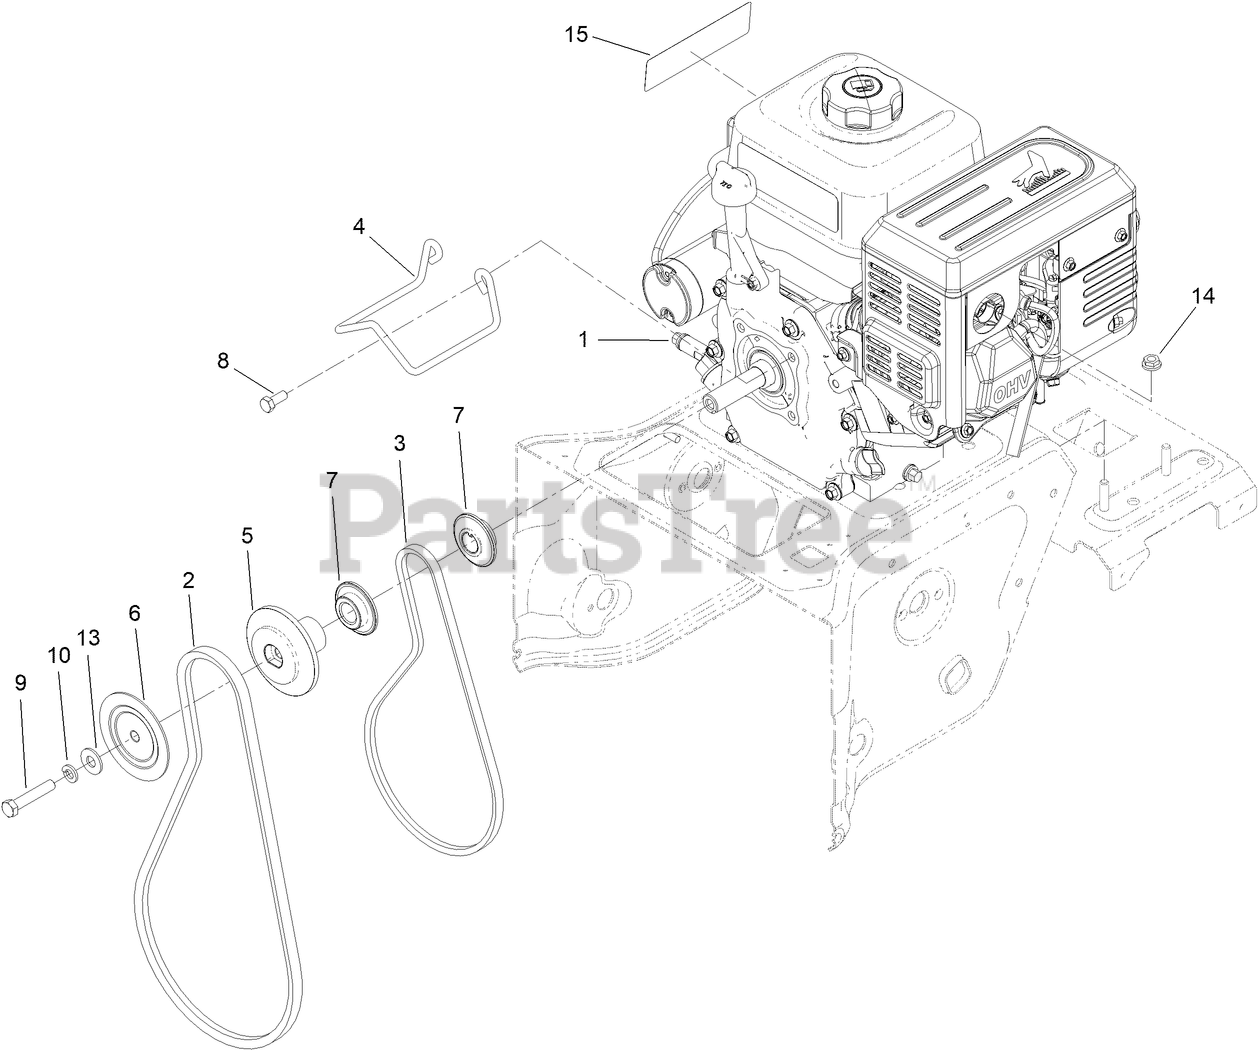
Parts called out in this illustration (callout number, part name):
1	G210FDS-1
2	BELT-V
3	BELT-V
4	GUIDE-BELT
5	PULLEY-AUGER, REAR
6	PULLEY-AUGER, FRONT
7	PULLEY-ENGINE, TRACTION
8	SCREW-HH
9	SCREW-HH
10	WASHER-LOCK
13	WASHER-FLAT
14	NUT-HF
15	DECAL - 212CC OHV
